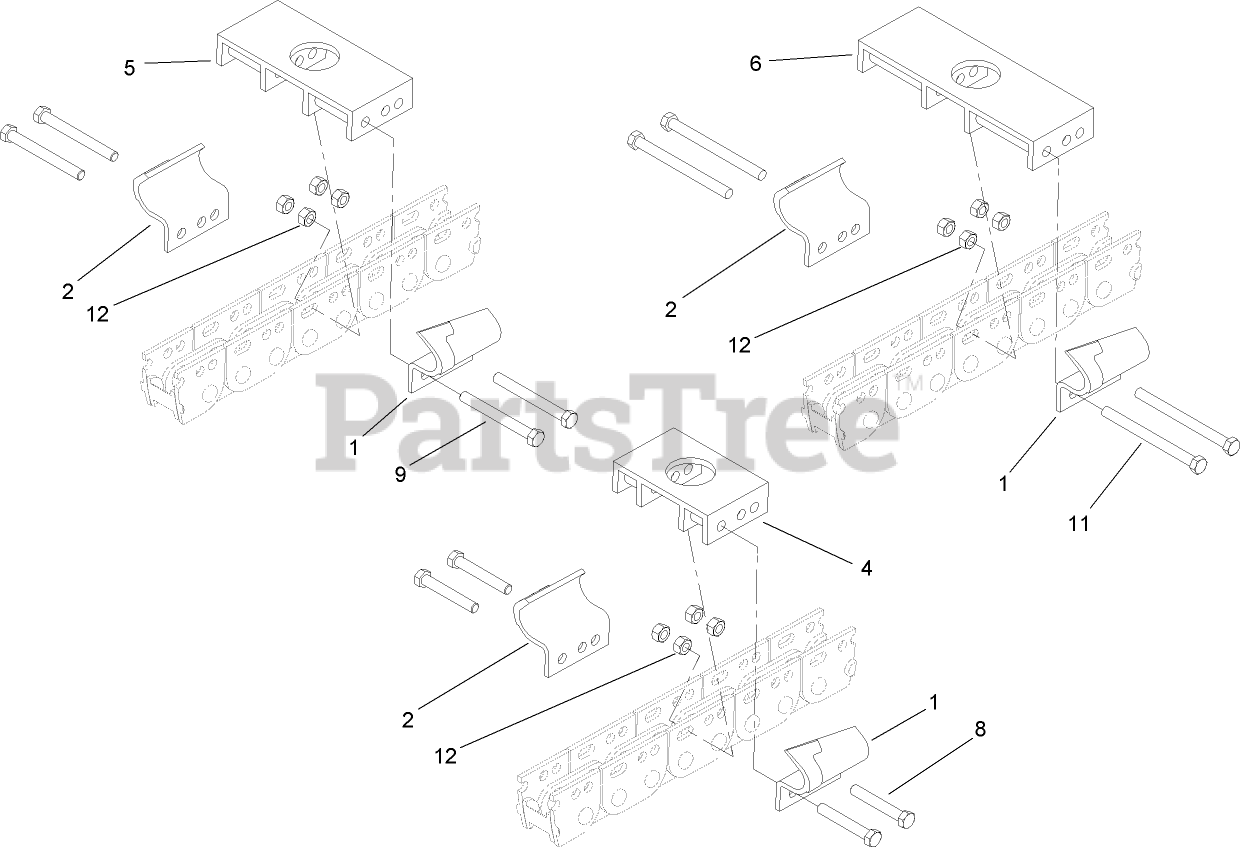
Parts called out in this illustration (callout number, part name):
1	TOOTH-SOIL, LH
2	TOOTH-SOIL, RH
4	ADAPTER-8 Inch
5	ADAPTER-10 Inch
6	ADAPTER-12 Inch
8	SCREW-HH
9	SCREW-HH
11	SCREW-HH
12	NUT-LOCK
